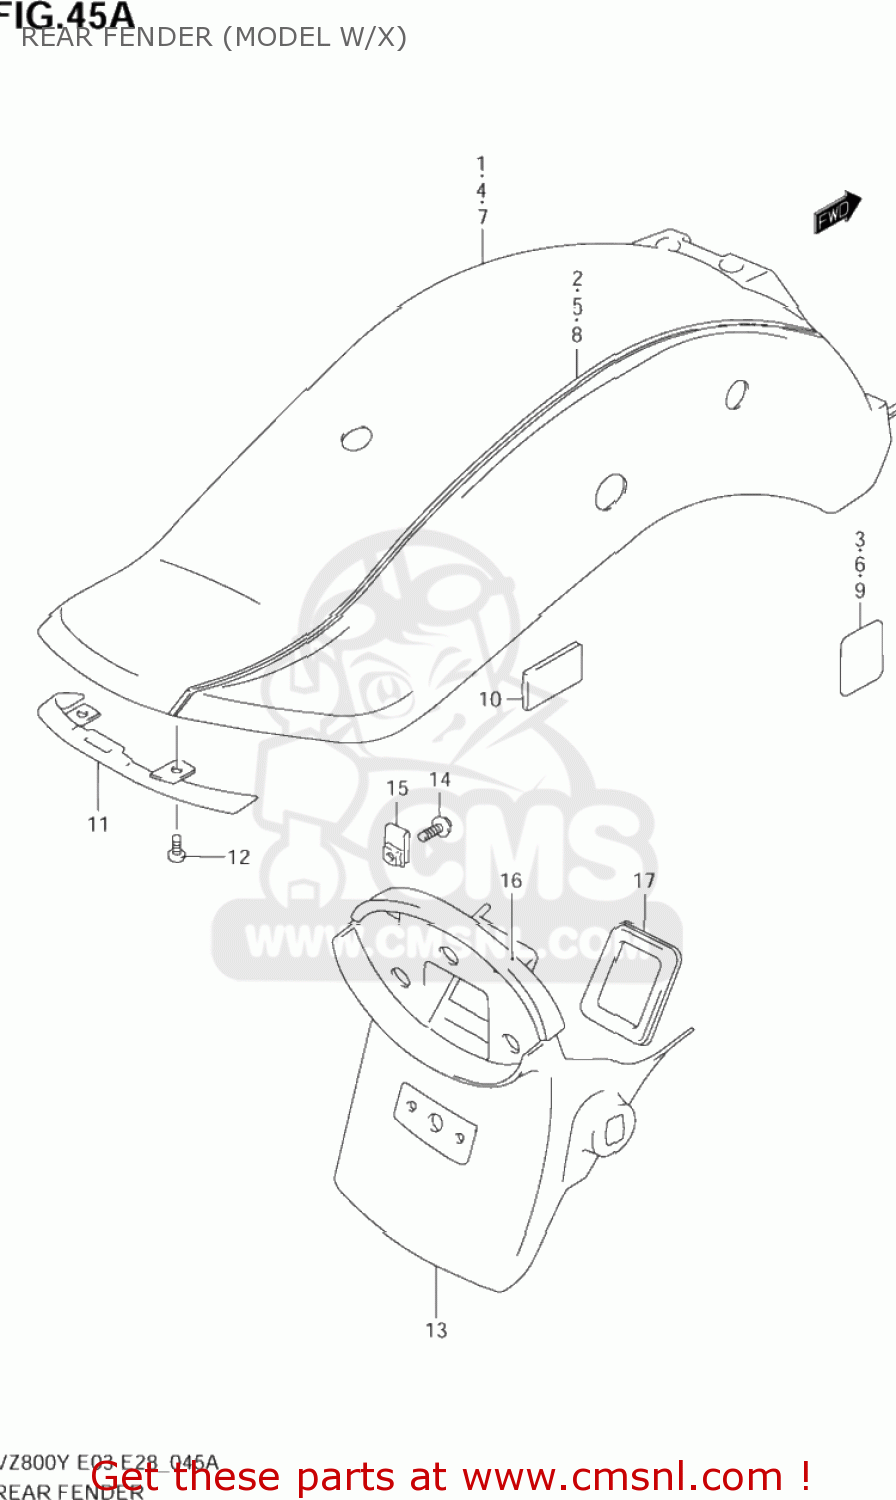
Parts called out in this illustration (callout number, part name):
1	FENDER,REAR
2	TAPE SET,RR FENDER
3	PAD
4	FENDER,REAR
5	TAPE SET,RR FENDER
6	PAD
7	FENDER,RR
8	TAPE SET,RR FENDER
9	PAD
10	CUSHION
11	COVER,RR FENDER RR
12	SCREW
13	EXTENSION,RR FENDER
14	SCREW
15	PLATE,FRAME COVER
16	CUSHION,RR FENDER EXTENSION
17	CAP,RR FENDER EXTENSION
